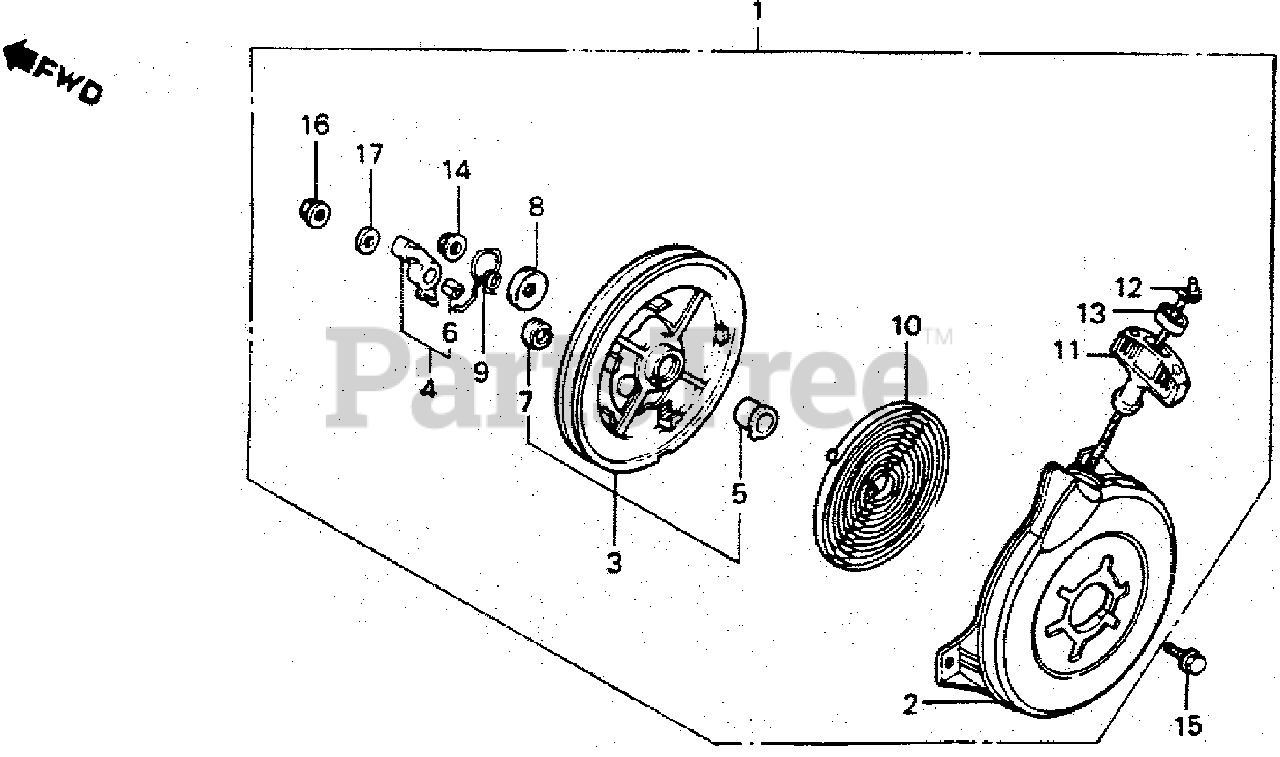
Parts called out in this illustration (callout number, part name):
1	STARTER ASSY., RECOIL *R8* (BRIGHT RED) (NOT AVAILABLE)
2	CASE, STARTER *R8* (BRIGHT RED)
3	REEL, STARTER (NOT AVAILABLE)
5	BOSS, REEL
6	BUSH, RATCHET
7	BUSH, REEL STARTER
8	PLATE, FRICTION
9	SPRING, FRICTION
10	SPRING, RETURN
11	GRIP, STARTER
12	ROPE, RECOIL STARTER (#5X55")
13	SUPPORT, GRIP
14	NUT, SELF-LOCK (8MM)
15	BOLT-WASHER (6X10)
16	NUT, FLANGE (5MM)
17	WASHER, PLAIN (5MM)
